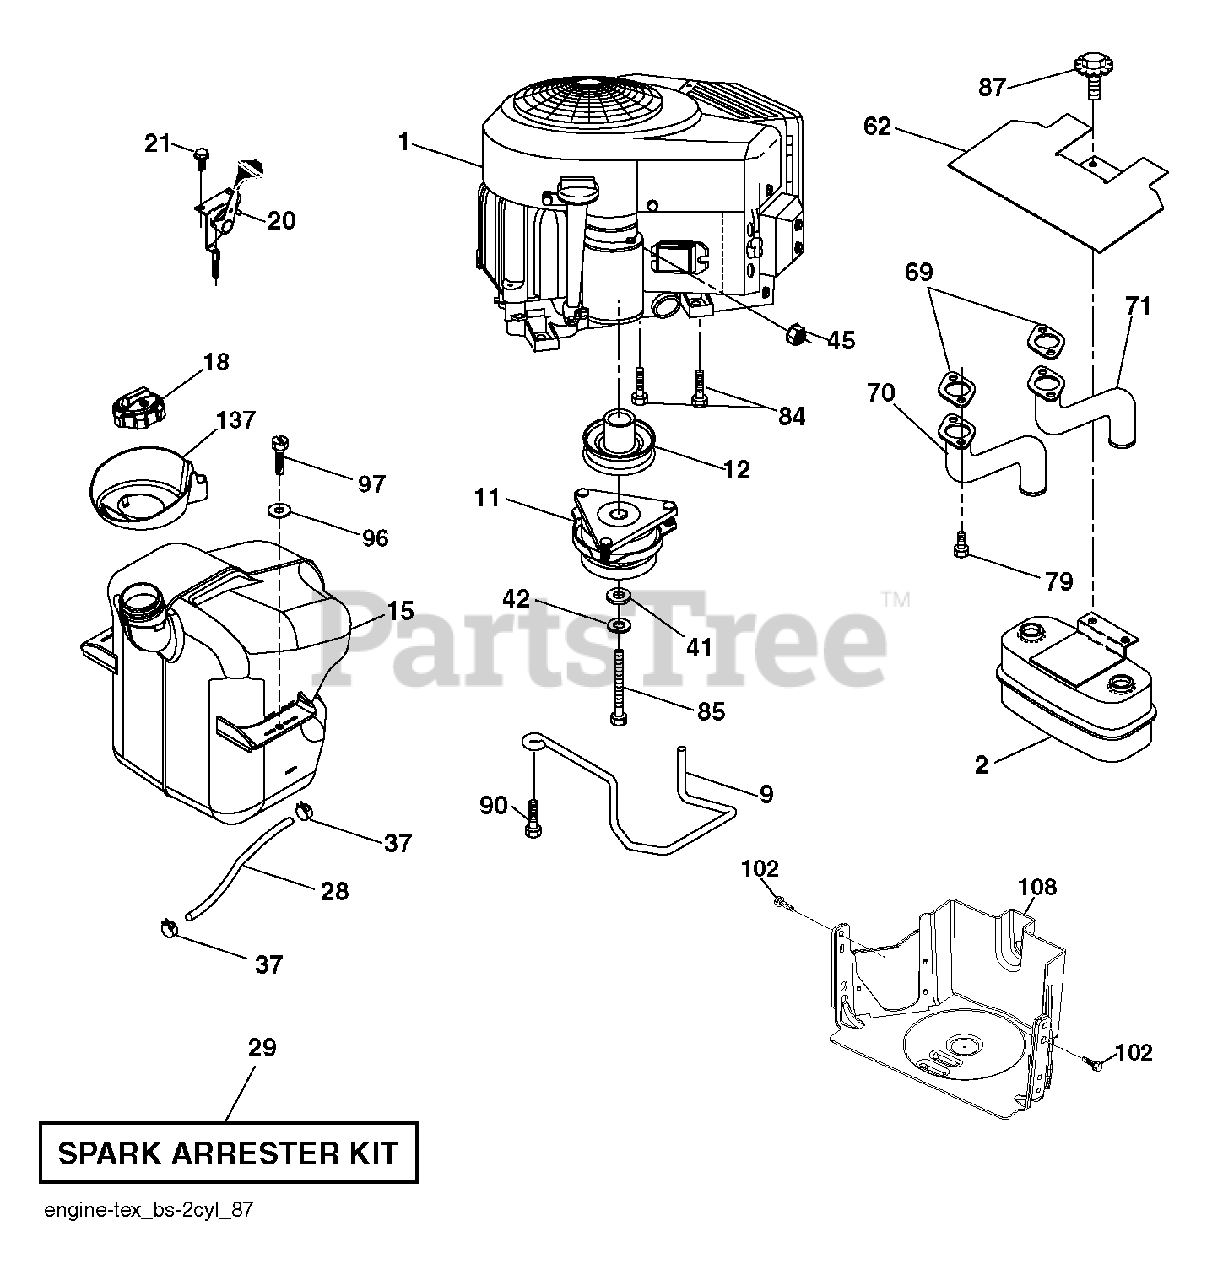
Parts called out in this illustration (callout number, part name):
2	MUFFLER.ASM.TWN.EXTNDED.DFLCTR
9	KEEPER.BELT.ENGINE.4.2
11	CLUTCH.ELECTRIC.LT.48"*
12	PULLEY.ENGINE.TUFFTORQ
15	FUEL TANK TANK. ASSEMBLY. EXTE
18	CAP.ASM.FUEL.2.25"TOP.TURN
20	CONTROL.TH/CK.COBRA.B&S.TWN.
21	SCREW.#10 X 0.750.BOS
28	LINE.FUEL.20
29	KIT.SPARK ARRESTOR 794945 B&S
37	HOSE CLAMP
42	LOCKWASHER
45	NUT
62	SHIELD.HEAT.MUFFLER
69	GASKET.MUFFLER
70	RP.EXHAUST.TUBE.LH.BS/TWIN
71	EXHAUST.TUBE.RH.BS/TWIN
79	SCREW.SOCKET.HEAD.5/16-18
84	SCREW.3/8-16
85	BOLT HEX 7/16-20X4-1/4"
87	BOLT, 5/16-18 X 1 3/4
90	SCREW 3/8-16X1
97	SCREW HEXWSHR 1/4-20X3/4
102	SCREW 5/16-18X1
108	COVER PULLEY
